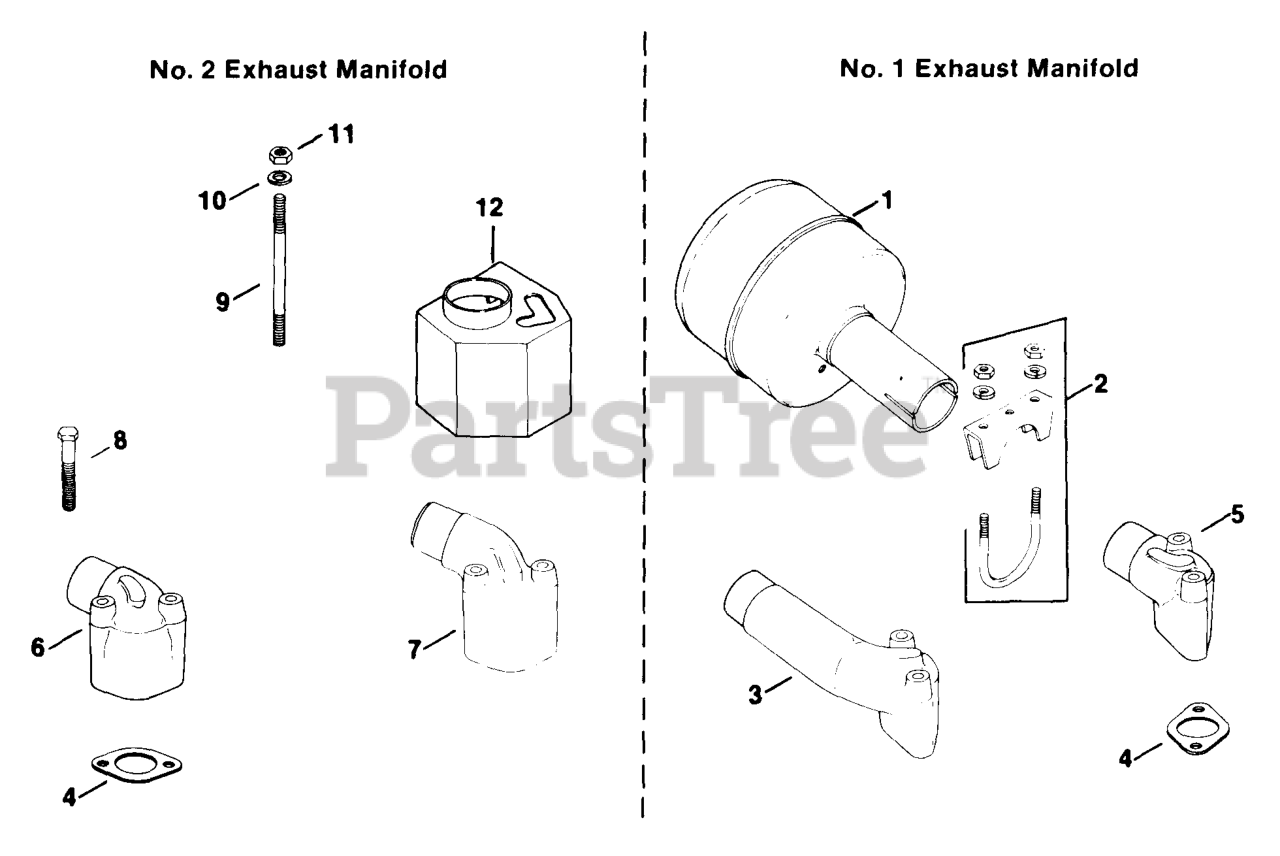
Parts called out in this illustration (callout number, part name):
4	GASKET - USE 52 041 14
5	MANIFOLD - (#DSC)
8	SCREW - USE 25 086 05
9	STUD - USE 52 072 13
10	Washer, split lock 5/16
11	Nut, hex. hd. 5/16-18
12	HEATER - DISCONTINUED
